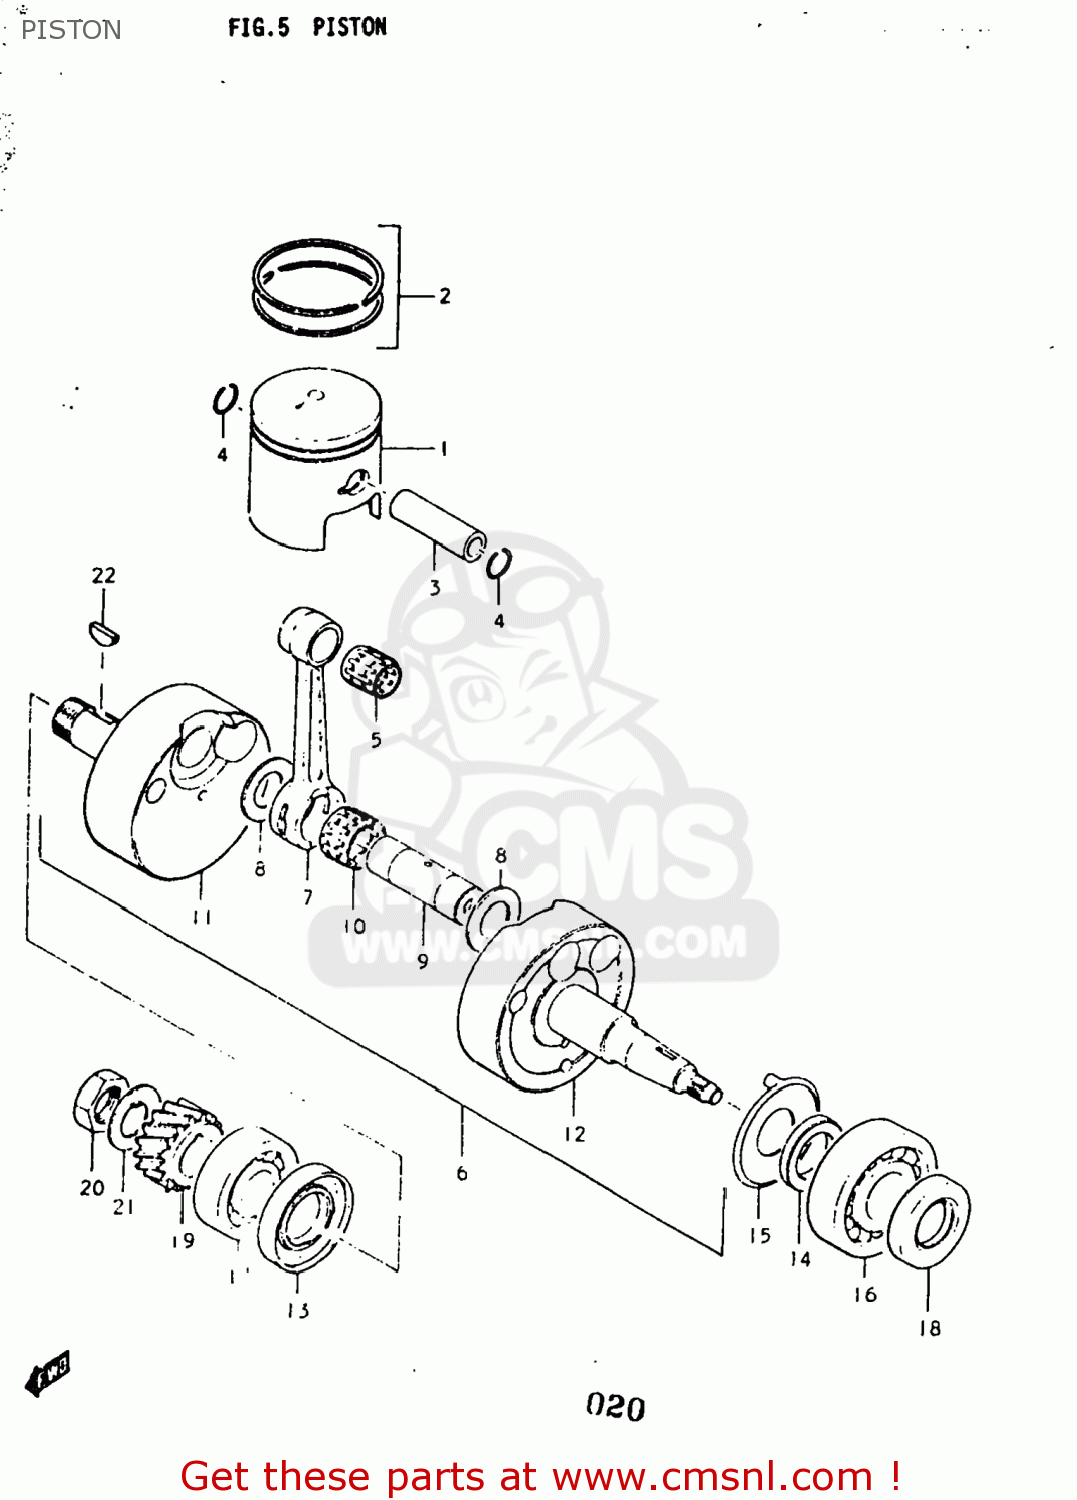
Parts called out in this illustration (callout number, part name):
1	PISTON
2	RING SET,PISTON
3	PIN,PISTON
4	RING,SNAP 14MM
5	BEARING
6	CRANKSHAFT ASSEMBLY
7	CONNECTING ROD
8	WASHER
9	PIN,CRANK
10	BEARING
11	CRANKSHAFT
12	CRANKSHAFT,LEFT
13	SEAL,OIL(26X52X8)
14	SPACER
15	PLATE,CRANKSHAFT OIL GUIDE
16	BEARING(25X62X17)
17	BEARING
18	OIL SEAL
19	GEAR,PRIMARY DRIVE
20	NUT
21	WASHER
22	KEY
